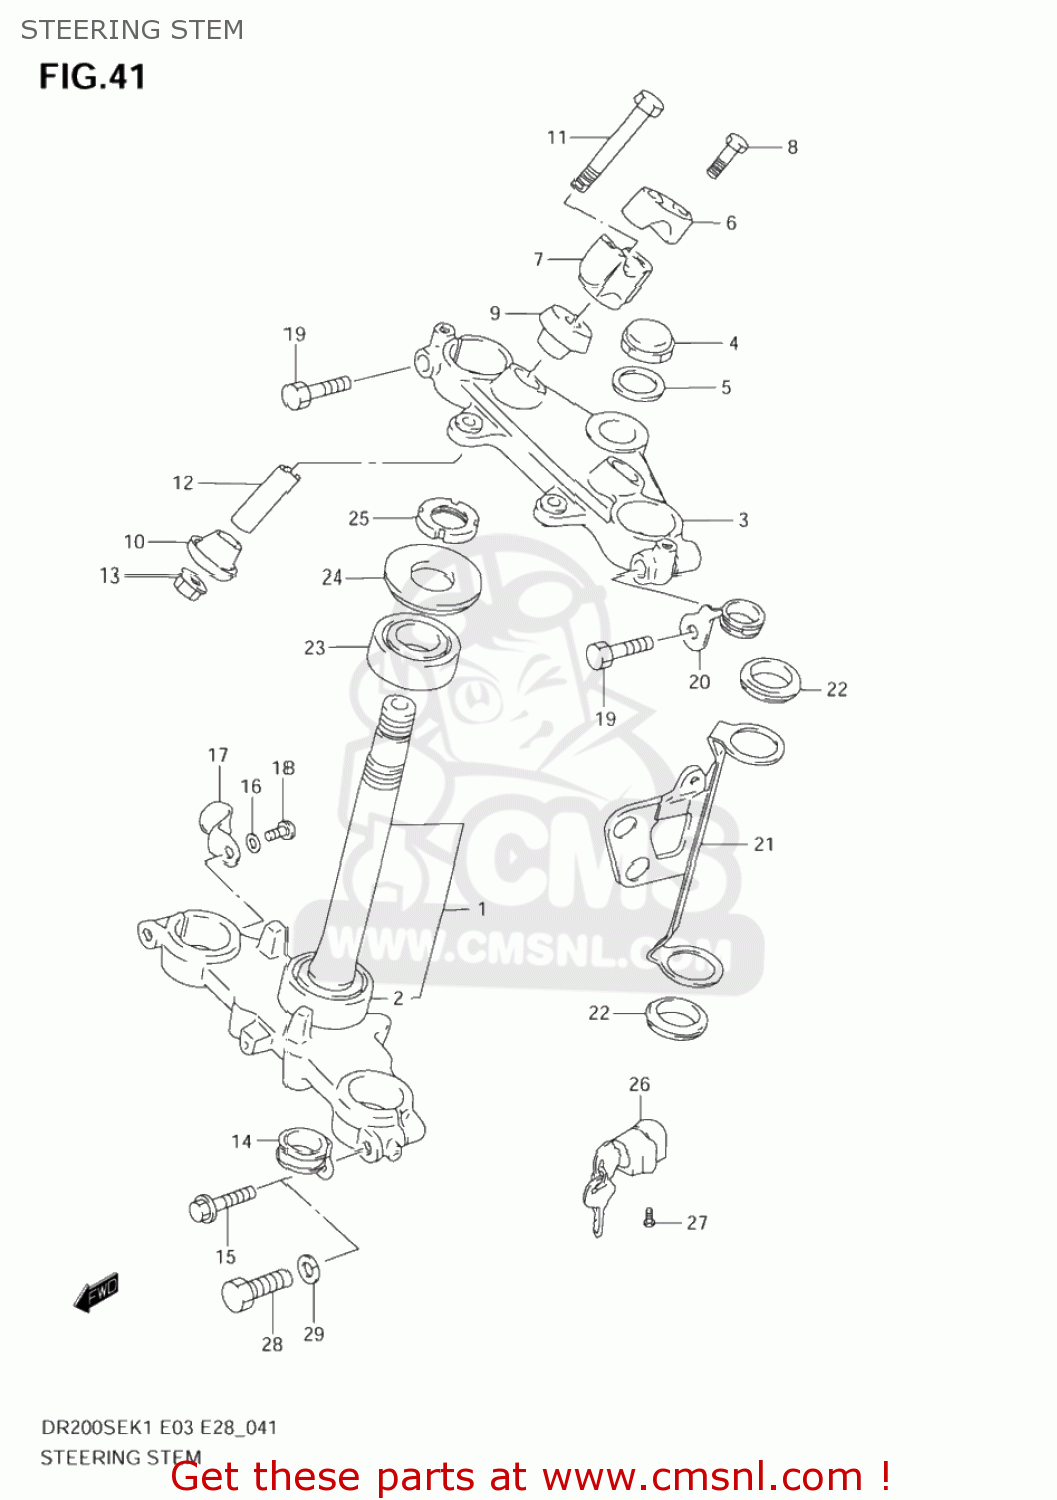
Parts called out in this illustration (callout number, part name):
1	STEM,STEERING
2	BEARING(30X55X17)
3	HEAD,STEERING STEM
4	NUT,CAP
5	WASHER
6	HOLDER,HANDLE UPR
7	HOLDER,HANDLEBAR LWR
8	BOLT
9	RUBBER,HANDLE HOLDER
10	CUSHION,RUBBER UNDER
11	BOLT,HANDLE HOLDER(10X70)
12	SPACER
13	NUT
14	CLIP,LOWER
15	BOLT
16	WASHER,LOCK
17	CLIP
18	SCREW
19	BOLT
20	CLIP
21	BRACKET,HEADLAMP,R
22	CUSHION,HEADLAMP HSG BRACKET
23	BEARING(25X47X15)
24	SEAL,STEERING UPR DUST
25	NUT,STEERING
26	LOCK SET,STEERING
27	SCREW
28	BOLT,INNER TUBE FITTING
29	WASHER
